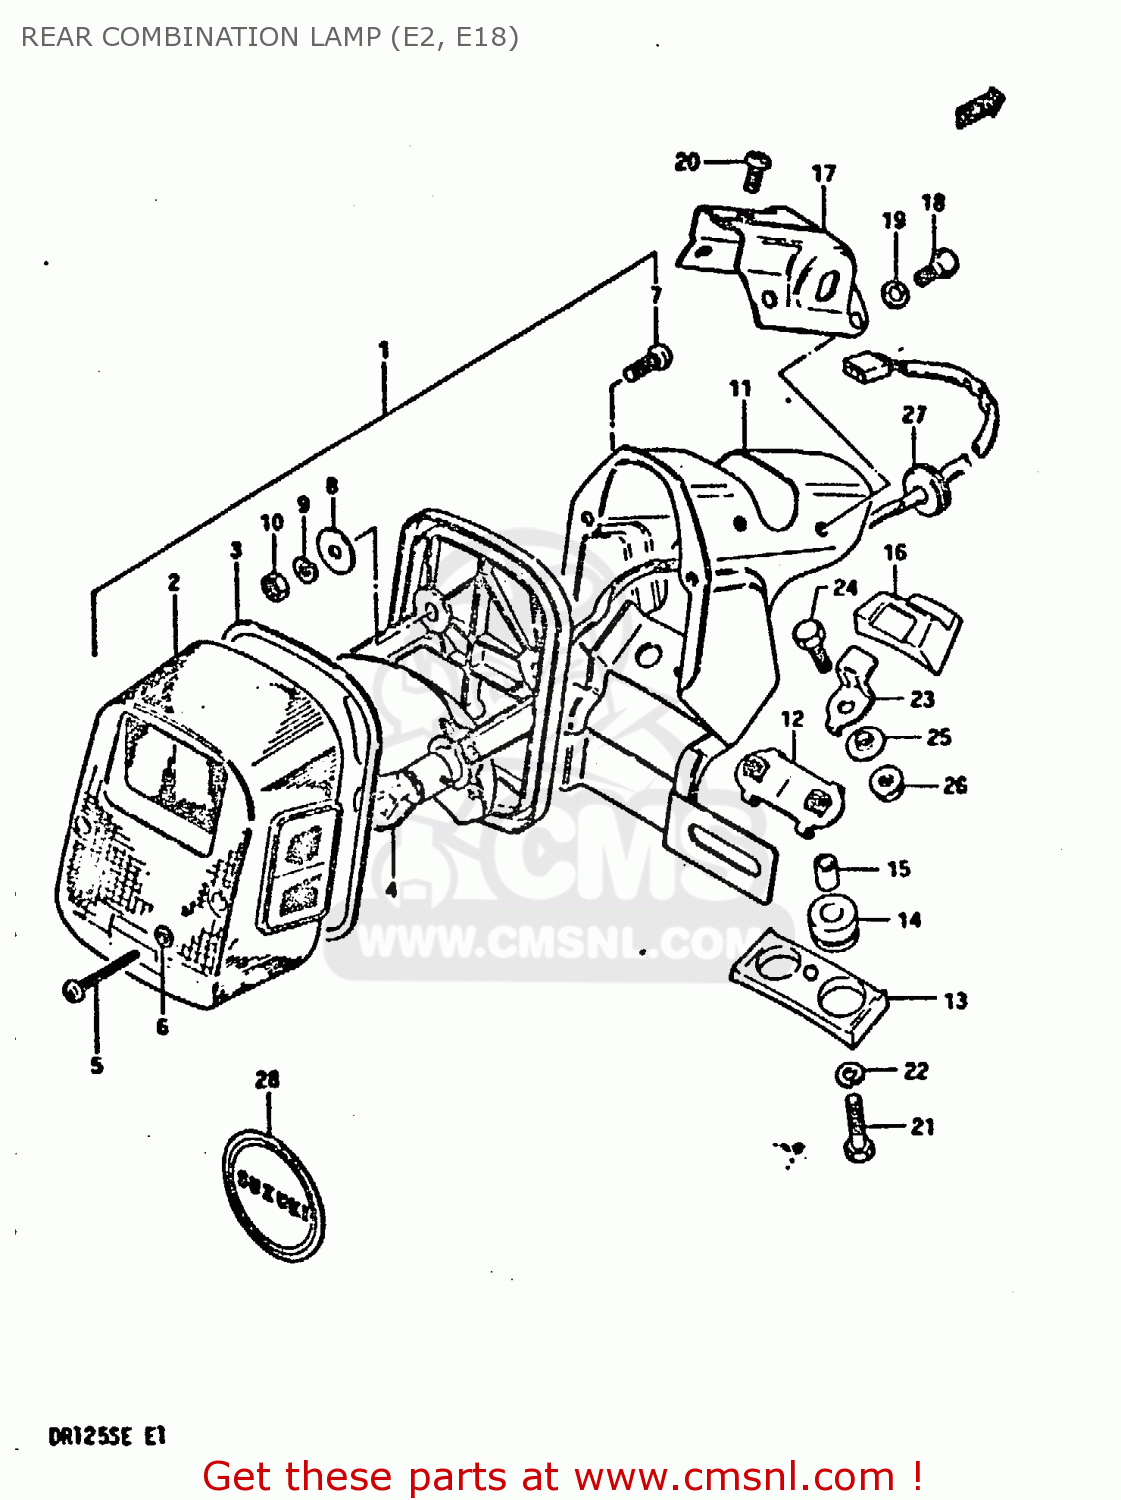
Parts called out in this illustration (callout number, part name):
1	LAMP UNIT, REAR COMBINATION
2	LENS,RR COMBI
3	GASKET (NAS)
4	BULB 12V21/5W
5	SCREW
6	GASKET (NAS)
7	SCREW
8	WASHER,REAR COMBINATION LAMP
9	LOCK WASHER
10	NUT
11	BRACKET UNIT
12	PLATE
13	CUSHION
14	CUSHION
15	SPACER
16	CUSHION,REAR COMBINATION LAMP
17	PLATE
18	BOLT
19	WASHER
20	SCREW 6X12
21	BOLT
22	WASHER,LOCK
23	PLATE,RR COMBINATION LAMP
24	BOLT
25	WASHER,LOCK
26	NUT
27	GROMMET
28	EMBLEM, REAR
